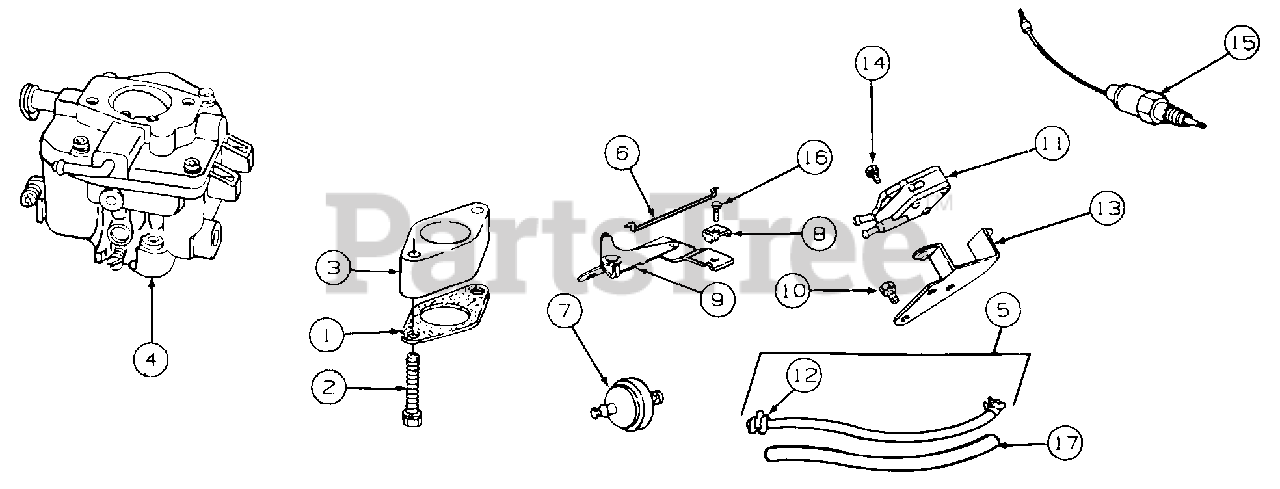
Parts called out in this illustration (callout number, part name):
1	Gasket, Carburetor Mounting
2	Screw, Sems
3	Spacer, Carburetor
4	Carburetor Assembly
5	Line, Fuel (Cut as Necessary)
6	Link, Choke
7	Filter, Fuel
8	Clamp, Casing
9	Bracket, Choke
10	Screw, Sems
11	Pump, Fuel
12	Clamp, Fuel Line
13	Bracket, Fuel Pump
14	Screw, Mtg.
15	Solenoid
16	Screw, Hex Head
17	Insulation, Fuel Line
